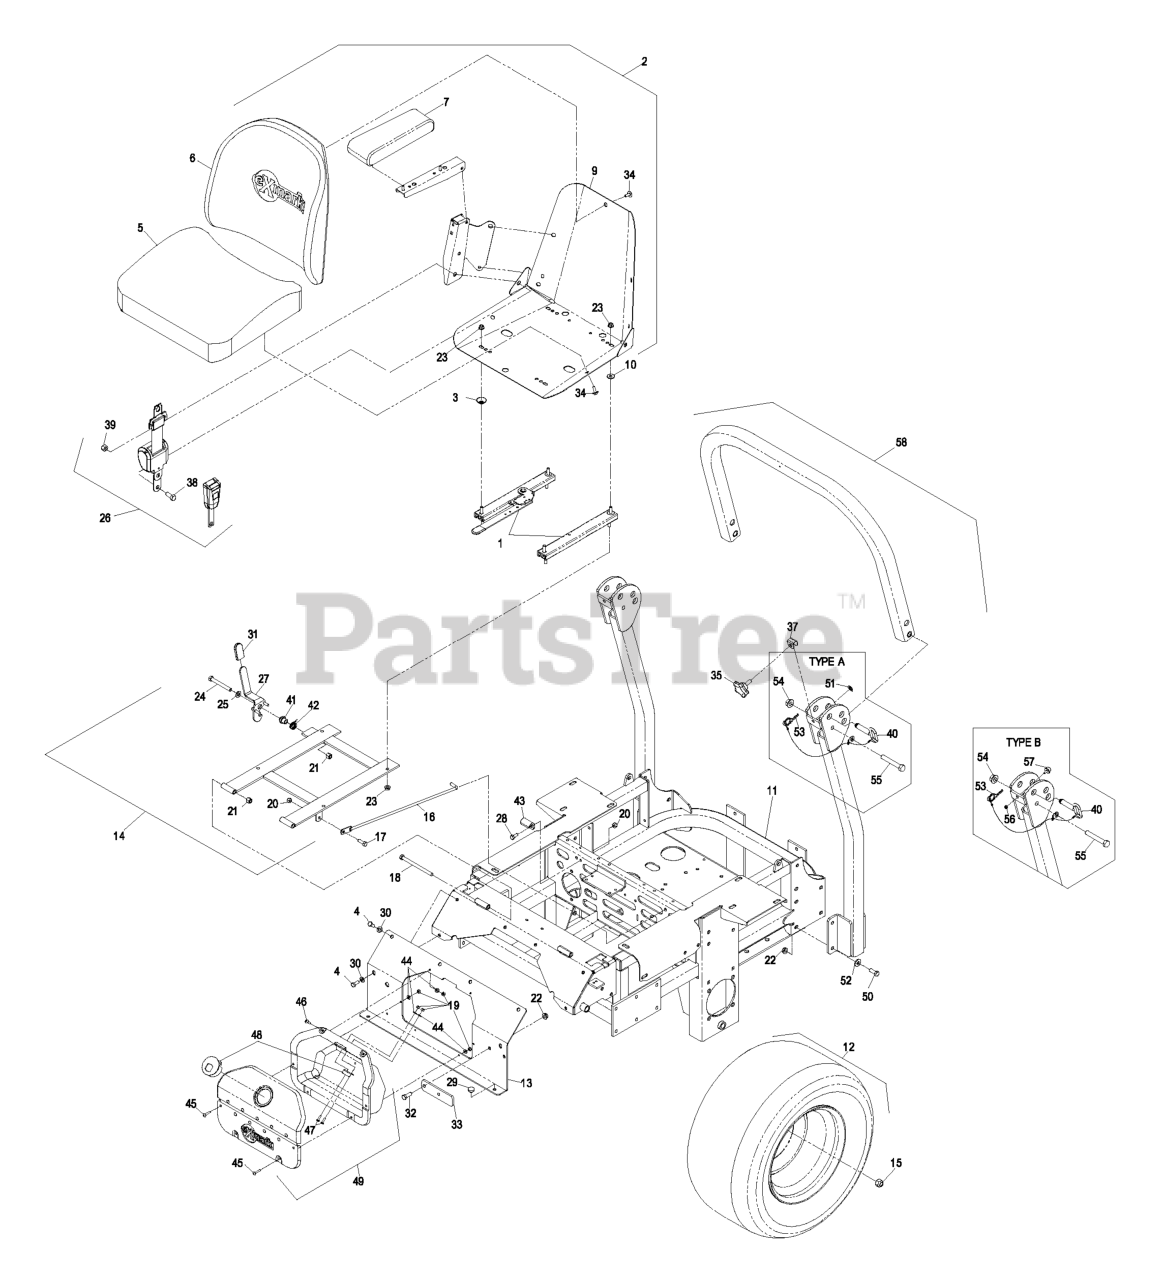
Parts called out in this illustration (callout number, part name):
1	TRACK-SEAT
2	KIT,SEAT W/ARMREST ADJ.
3	SPACER-TRACK
4	SCREW-HH
5	CUSHION,SEAT BOTTOM
6	CUSHION,SEAT BACK
7	CUSHION,ARMREST RH
9	FRAME-SEAT
10	WASHER-FLAT
13	ASM, CONSOLE W/DECALS
14	ASM,SEAT FRAME
15	NUT-LUG
16	ROD-HOLDUP, SEAT
17	SCREW-HH
18	SCREW-HH
19	NUT-LOCK, NI
20	NUT-LOCK, NI
21	NUT-LOCK, NI
22	NUT-HHF, WHIZ
24	SCREW-HH
25	WASHER-FLAT
27	LATCH ASM
28	SCREW-HH
30	WASHER-PLAIN
31	GRIP-LEVER
32	SCREW-HH
33	STOP-BRAKE, PARK
34	BOLT-SEAT
36	SCREW-HH
38	SCREW-HH
39	NUT-LOCK, NI
40	PIN-FOLD, ROPS
41	BUSHING-LATCH, SEAT
42	SPRING-TORSION
43	CATCH-LATCH, SEAT
44	WASHER-FLAT
46	SCREW-HEAD, TRUSS
47	SCREW-PPH
48	LATCH,CUBBY
49	ASM,CUBBY
50	SCREW-HH
51	NUT-PUSH
52	WASHER-BELLEVILLE
53	HAIRPIN
55	SCREW-HH
56	NUT-LOCK, NI
57	BUMPER-RUBBER
58	KIT, ROPS LZ >510,000
